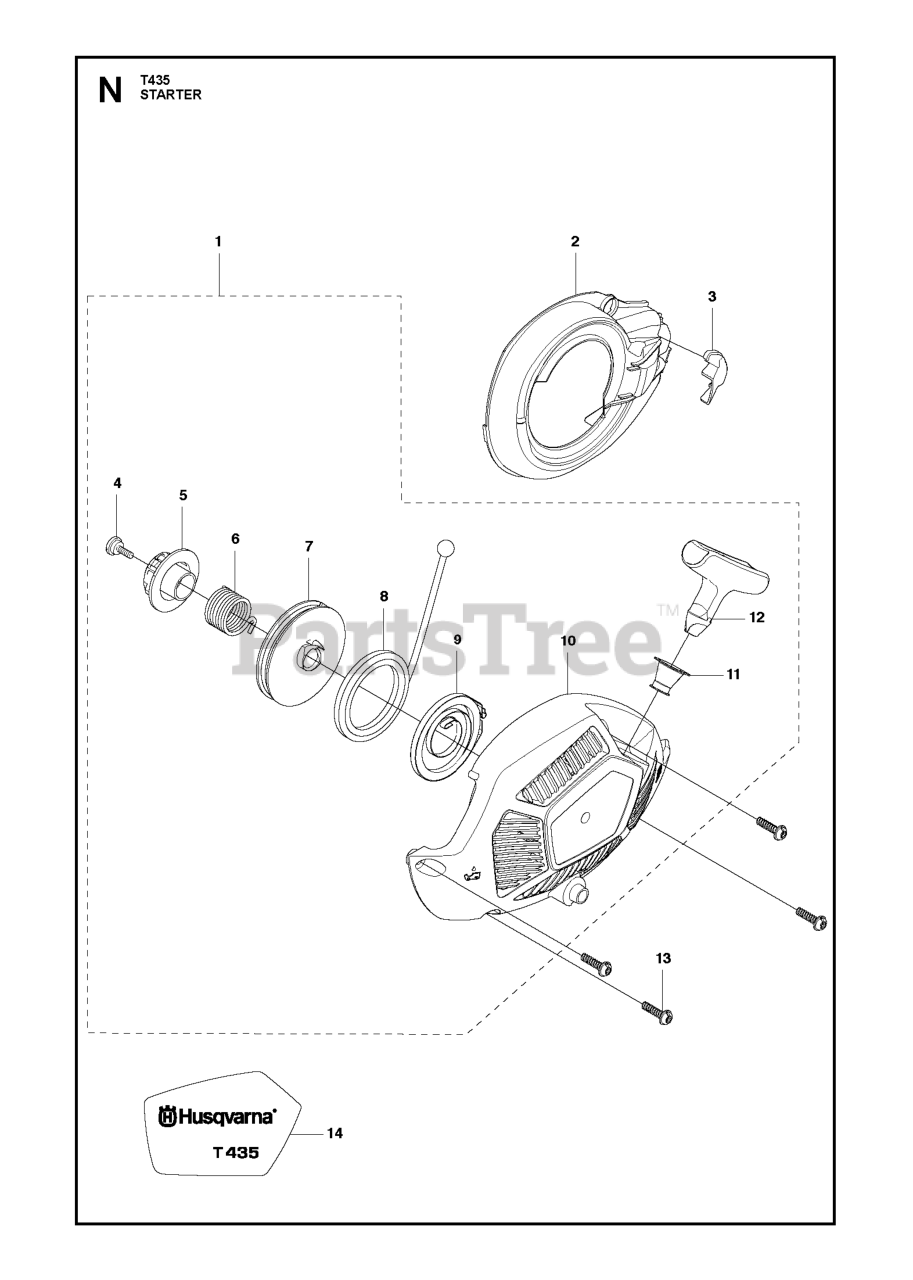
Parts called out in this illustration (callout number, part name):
5	WASHER BRB 8.4X17
6	LOCKNUT M8
8	BEARING HOUSING
9	BOLT
10	WASHER BRB 8.4X17
11	LOCKNUT M8
13	FUEL TANK BUSHING
18	ROD
21	NUT FLANGE - M6
24	SCREW EHHFM
25	ADJUSTING ROD
26	NUT FLANGE - M6
29	ROD
33	Screw M10x25
34	LOCKNUT M6
